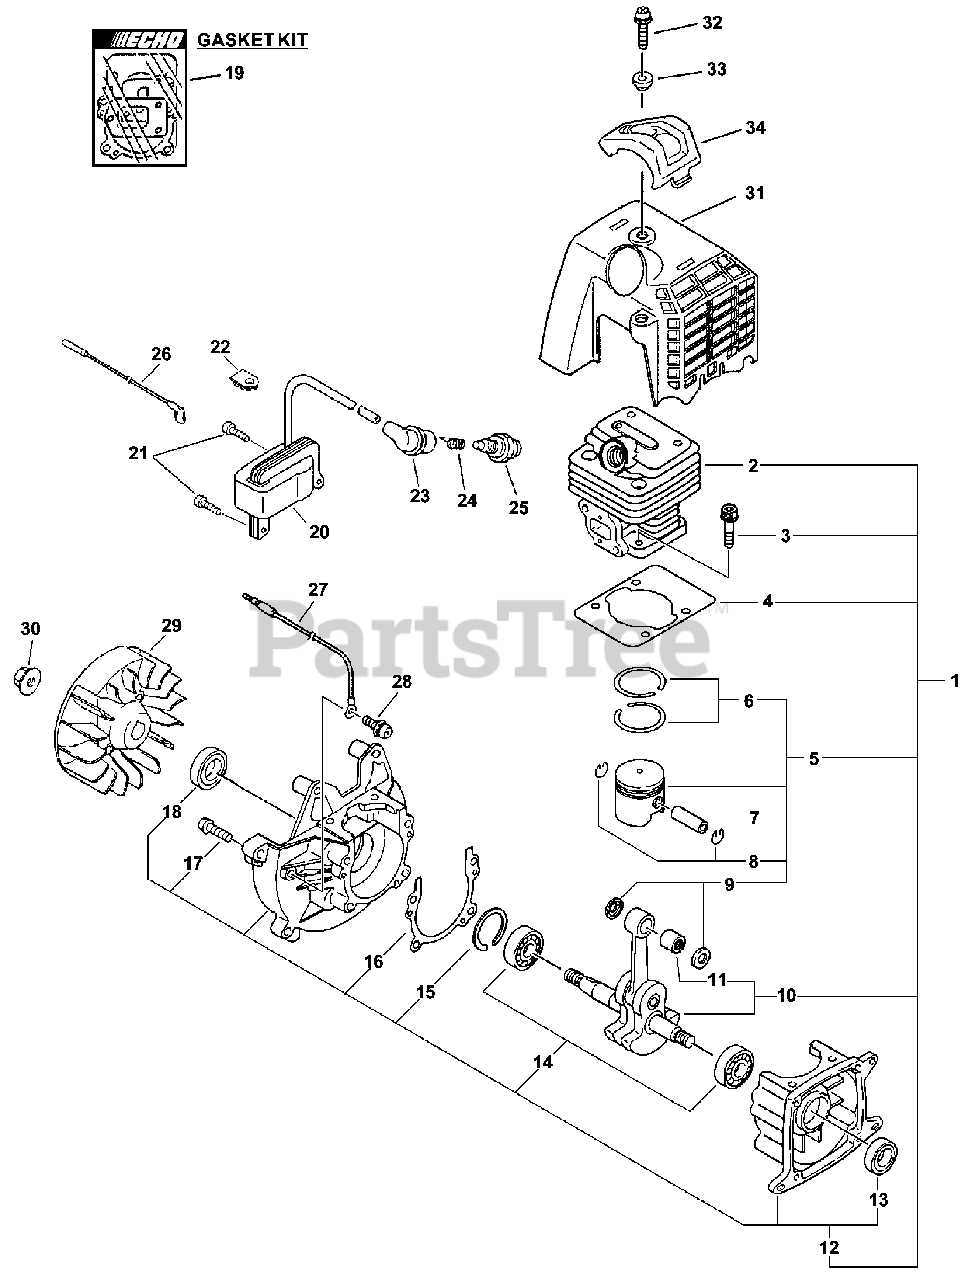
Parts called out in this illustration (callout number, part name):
1	SHORT BLOCK
2	CYLINDER
3	BOLT 5×22
4	GASKET, CYLINDER
5	PISTON KIT
6	RING, PISTON
7	PIN, PISTON 8
8	RING, SNAP
9	WASHER, THRUST
10	CRANKSHAFT ASSY
11	BEARING, NEEDLE 8
12	CRANKCASE KIT
13	SEAL, OIL 12
14	BEARING, BALL 6001
15	RING, SNAP 28
16	GASKET, CRANKCASE
17	BOLT 5×25
18	SEAL, OIL 12
19	GASKET KIT
20	COIL, IGNITION
21	BOLT 5×16
23	CAP, SPARK PLUG
24	TERMINAL, SPARK PLUG
25	SPARK PLUG - BPM-7Y
26	LEAD - IGNITION 145 MM
27	LEAD - GROUND
28	SCREW 5×10
29	FLYWHEEL
30	NUT, FLANGE M8
31	COVER, ENGINE - GRAY
32	BOLT 5×16
33	COLLAR 5
34	GUARD, TOP
